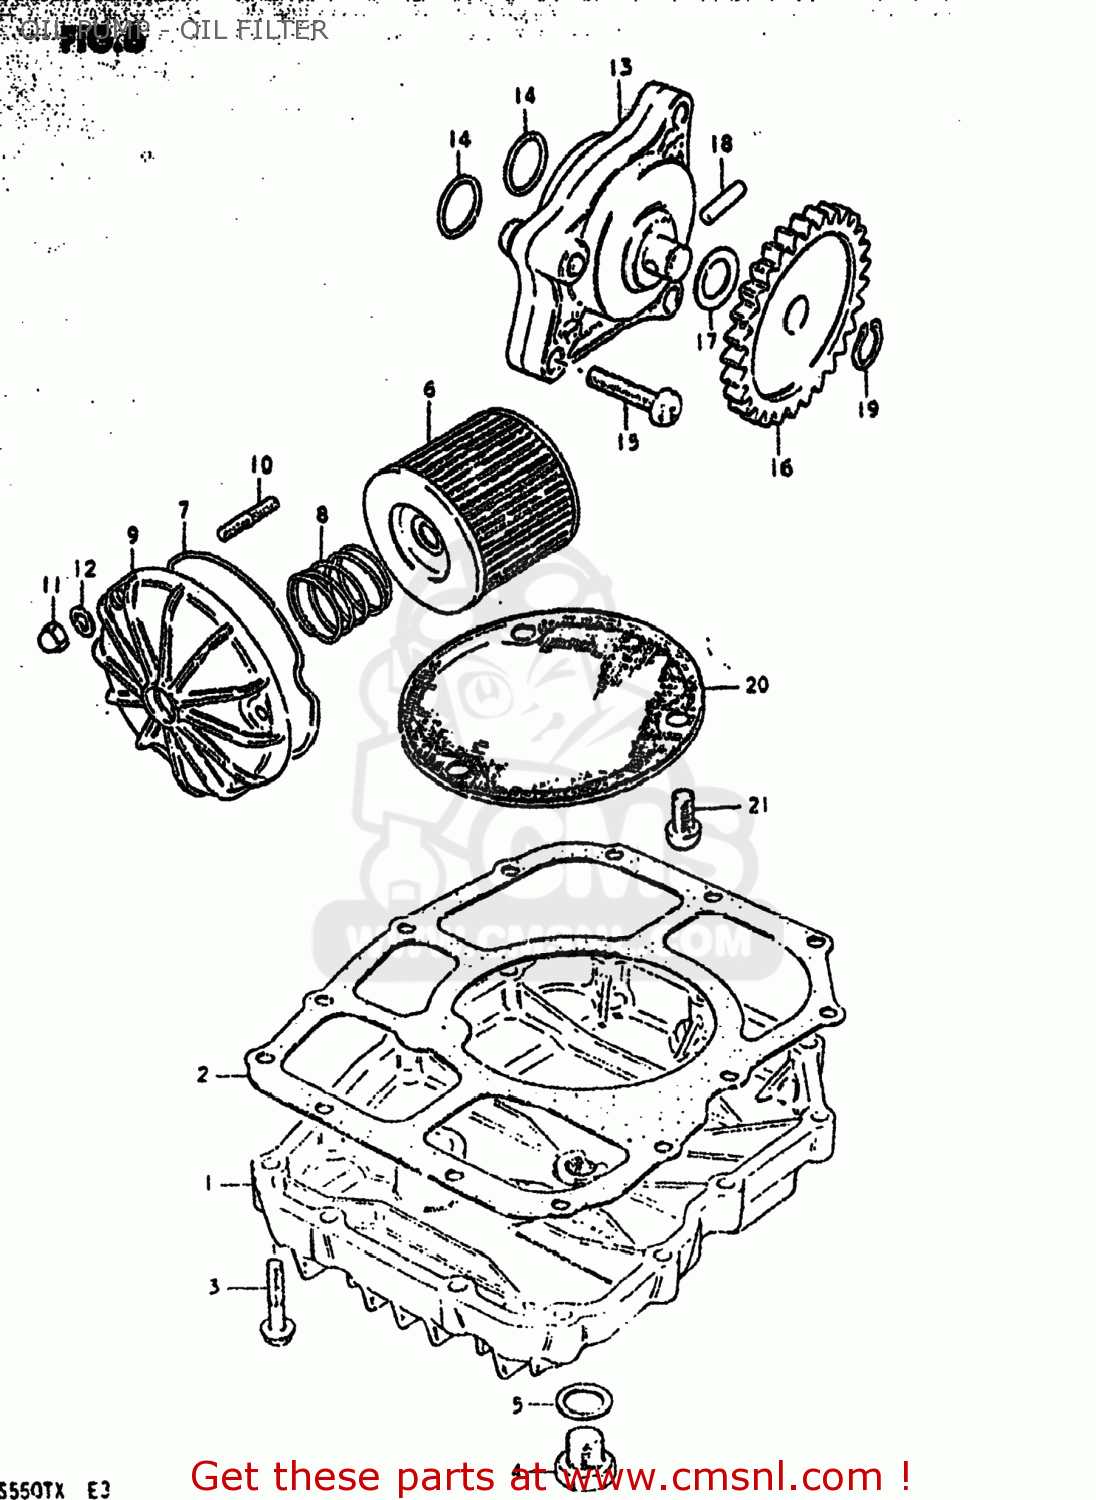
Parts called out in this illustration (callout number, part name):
1	PAN,OIL
2	GASKET,OIL PAN (MCA)
3	BOLT
4	PLUG
5	GASKET(14X19.2X2) (NAS)
6	FILTER ASSY,ENGINE OIL
7	O RING,OIL FILTER CHAMBER CAP
8	SPRING
9	CAP,ENGINE OIL FILTER
10	STUD 6X20
11	NUT
12	WASHER
13	PUMP ASSEMBLY,ENGINE OIL
14	O RING(D:1.9,ID:13)
15	SCREW
16	GEAR,OIL PUMP DRIVEN
17	SHIM
18	PIN(4X15.8)
19	CIRCLIP
20	STRAINER,ENGINE OIL
21	SCREW 6X12
